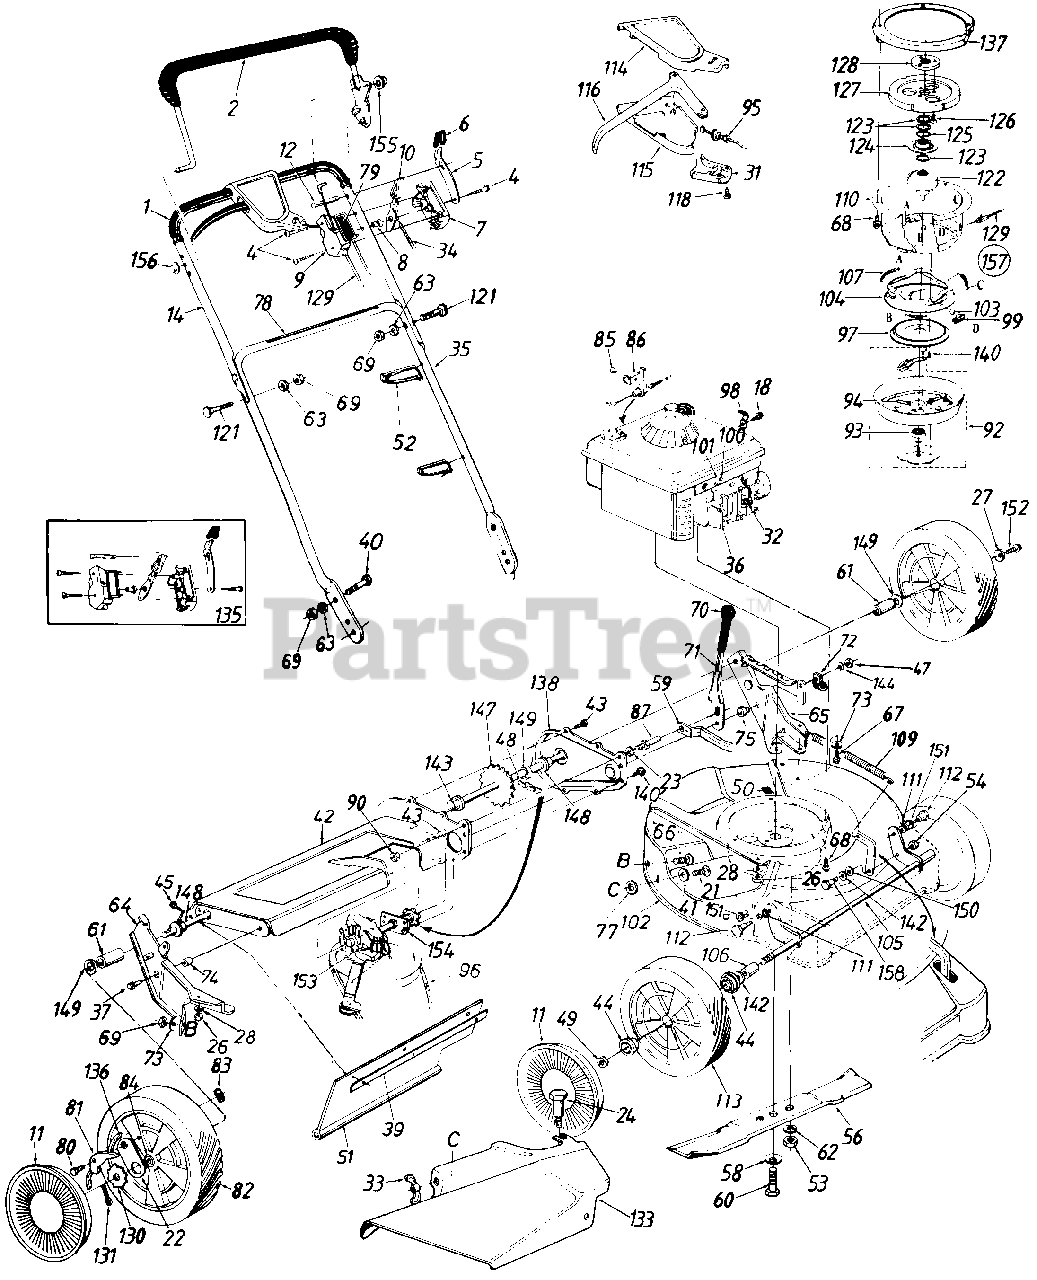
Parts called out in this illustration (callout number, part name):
1	Grip
2	Control Handle Ass'y.-L.H.
4	Truss Mach. Scr. #12 x 1.50" Lg.
5	Lockout Spring
6	Spring Lever Knob
7	Control Panel Half
8	Control Disc Pin
9	Clutch Panel Half
10	Throttle Control Lever
11	Hub Cap
12	Lock Pin 3/4" Dia. x 1.75"
14	Upper Handle
18	Hex B-Tap Scr. #10 x .38"
21	Carriage Bolt 1/4-20 x .62"
22	Pawl Plate
23	L-Wash. 3/8" I.D.
24	Shoulder Bolt .312" Dia. x .18" Lg. Special
26	Hex Nut 1/4-20 Thd.*
27	Bell-Wash. 1/4" I.D.
28	L-Wash. 1/4" I.D.
31	S.P. Control Cover
32	Spark Plug Insulator
33	Wing Nut
34	Throttle Control Wire 58" Lg.
35	Lower Handle
36	Engine
37	Hex L-Wash. TT-Tap Scr. 3/8-16 x 1" Lg.
39	Retaining Strip
40	Truss Mach. Scr. 5/16-18 x .75" Lg.
41	Fl-Wash. .344" I.D. x .62"
44	Flange Ball Bearing 1/2" I.D.
45	Hex AB-Tap Scr. 1/4 x .62"
47	Hex Patch L-Nut 3/8-24 Thd.
48	#48 Chain .500" Pitch x 30 0 Links
49	Hex L-Nut 1/2-20 Thd.
51	Rear Flap 3.75" x 17.30" Lg.
52	Cable Tie
53	Hex Nut 3/8-24 Thd. (Gr. 8)
54	Hex Jam Nut 3/8-16 Thd.
56	21" Blade
58	Bell-Wash. .46" I.D. x .88" O.D.
59	Height Adj. Connecting Arm
60	Hex Bolt 7/16-20 x 2.0" Lg. (Grade 5)
61	Spacer .513" I.D. x .703" O.D. x .69" Lg.
62	L-Wash. 3/8" I.D.
63	L-Wash. 5/16" I.D.
64	R.H. Handle Wheel Brkt. Ass'y.
65	L.H. Handle Wheel Brkt. Ass'y.
66	Carriage Bolt 5/16-18 x .62"*
67	Hex Wash. Hd. B-Tap Scr. 5/16-18 x .5" Lg.
68	Hex Wash. Hd. TT-Tap Scr. 3/8-16 x 1.5" Lg.
69	Hex Nut 5/16-18 Thd.
71	Height Adj. Lever
73	Bell-Wash. 5/16" I.D.
74	Spacer .383" I.D. x .503" O.D.
75	Shld. Spacer .500" Dia. x .100"
77	Bolt Retainer 1/4 X .50" O.D.
78	Instruction Label
79	Control Label
80	Shld. Scr. .342" Dia. x .268"
81	Pawl
82	Wheel Ass'y. Comp.-Rear 8 x 2.0"
83	Flat Weld Nut 1/4-20 Thd.
84	Sleeve Bearing 1/2" I.D.
85	Pop Rivet .156" Dia. x .379"
86	Cable Bracket
87	Shld. Pin 3/8-24 x 1.43" Lg.
90	Hex Jam Nut 3/8-24 Thd.
92	Clutch Blade Housing Ass'y.
93	Ball Brg. .669" I.D. x 1.574"
94	Comp. Spring .35" O.D. x 2.0" Lg.
95	S.P. Cable x 50" Lg.
96	"V"-Belt
97	Clutch Cone
98	Casing Clamp
100	Hex B-Tap Scr. #10 x .62"
101	Casing Clamp
102	483/N 21" Deck Ass'y.
103	Steel Ball .50" Dia.
104	Brake Cup Cone
105	Front Axle Ass'y.
106	Sleeve .526" I.D. x .690" O.D. x .880" Lg.
107	Ext. Spring 1.75" Lg.
109	Extension Spring .75" O.D. x 8" Lg.
110	Clutch Housing
111	Intern. L-Wash. 3/8 I.D.
112	Shld. Bolt .623" Dia. x .425
113	Front-Wheel Ass'y. Comp. 8 x 2.0"
114	Self-Propelled Control Cover
115	Self-Propelled Control Cover
116	Control Lever
118	Fl-"C"-Sunk Hd. Tap Scr. #10 x .75" Lg.
121	Curved Carr. Bolt 5/16-18 x 1.38" Lg.
122	Fixed Pulley Adapter
123	Serrated Washer 1.0" I.D.
124	Serrated Pulley Half
125	Wave Washer 1.005" I.D.
126	Flat HD Tap Scr. 1/4-20 x .625" Lg.
128	Flywheel Adapter
129	Control Cable-49" Lg.
130	Ratchet Wheel 1.62" O.D.
131	Cotter Pin 1/8" Dia. x 1 00
133	Side Chute Deflector Ass'y.
135	Kit-Control Housing Comp.
136	Spring-Nylon
137	Engine Mounting Plate Cover
142	Fl-Wash. .510" I.D. x .75" O.D.
143	Hex Flange Brg. .506" I.D.
144	Fl-Wash. .385" I.D. x .87" O.D.
147	Rear Shaft Ass'y. 21.94" Lg.
148	Hex Flange Bearing .506" I.D. Plastic
149	Fl-Wash. .531" I.D. x .930" O.D.
150	Bell-Wash. .515" I.D. x 1.0" O.D.
151	Flanged Nyliner Brg.
152	Hex Bolt 1/4-20 x .62" Lg. (Grade 5)
153	Transmission Comp.
154	Hex Bearing Cup
157	Blade Brake Clutch Ass'y. Comp.
158	Shld. Bolt .5" Dia. x .295"
